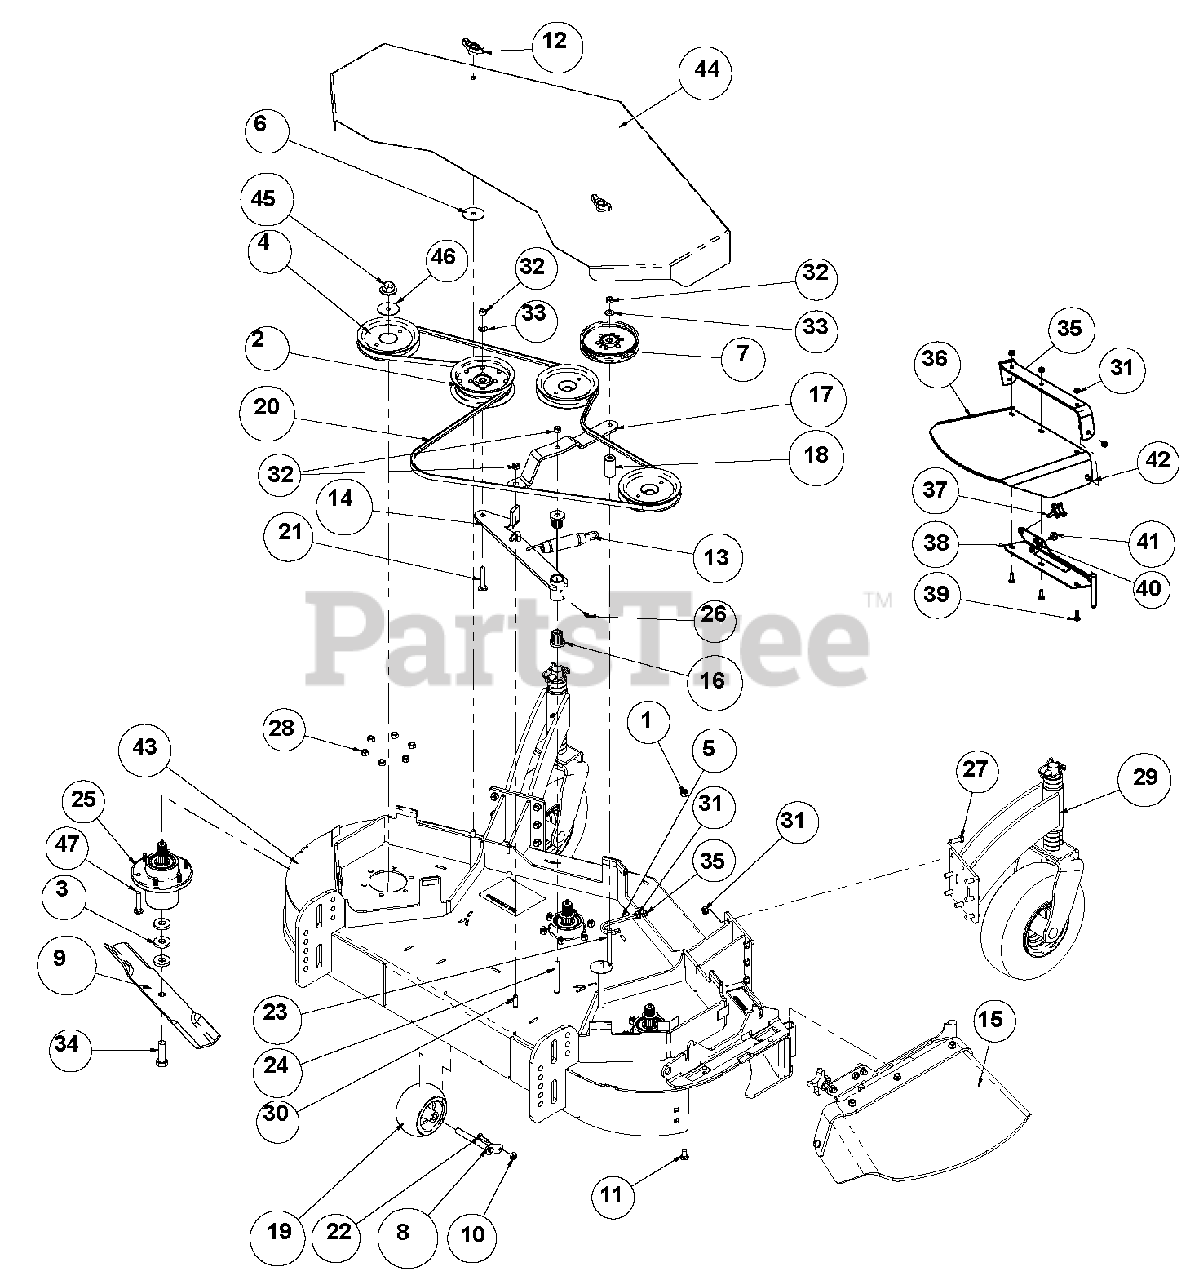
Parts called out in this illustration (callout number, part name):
1	Lochnut, .38-16 Nyloc
2	Pulley, Flat 5.0 x .38 W/Bearing
3	Washer, Blade
4	Pulley, Spline Spindle LSE
5	J-Bolt, 3/8-16 x 4.00 Y
6	Washer, .402 x 2.00 x .055 Fend Y
7	Pulley, FLAT 5.00 x .375 W/Bearing
8	Pivot, Retainer Weld
9	Blade, 18"
10	Nut-1/4" Flange Prevailing Tor
11	Bolt, .38-16 x .750 CRG 5
12	Knob, Locking
13	Spring, Tension
14	Arm, Idler
15	Assembly, Discharge Shield
16	Bearing, FLG M10 x M25 x M27 Fluted
17	Strap, Idler Pulley
19	Wheel, Gage
20	BELT, HB 109.3 EL AMD
21	Bolt, 3/8-16 x 2.25 CRG 5 Y
22	Bolt, 1/4-20 x 1.00 SQU SN Y
23	Bolt, 3/8 x 4 Short Neck Round Head
24	Bolt, 3/8-16 x 3.50 CRG 5 Y
25	Assembly, Spindle Housing
26	Fitting, 1/4-28 Straight Grease Zerk
27	Bolt, 3/8-16 x 1.00 Hex 5 Y
28	Nut, 3/8-16 STD Hex GR5 Y
29	Assembly, Wheel & Strut (see page 26 for parts)
30	Bolt, 3/8-16 x 1.25 CRG 5 Y
31	Locknut, 3/8-16 Whiz Y
32	Locknut, 3/8-16 Crown Y
33	Washer, .406 x .813 x x .065 Flat Y
34	Bolt, Hex .62-11 x 2.00 Grade 8
35	Strap, Rubber Discharge
36	Shield, Rubber Discharge
37	Knob, 3/8 x 1.25-4 Prong
38	Weldment, Discharge
39	Bolt, Round Head Square Neck .38-16 x 1.25 Grade 5
40	Locknut, 5/16-18 Whiz
41	Bumper, Rubber
42	Bolt, Round Head Square Neck .38-16 x 1.00 Grade 5
43	Weldment, 52 Gravely Deck w/Decals
44	Weldment, 52 Gravely Deck Shield w/Decal
45	Locknut, 3/4-16 Crown
46	Washer, .75 x 1.312 x .120
47	Bolt, .38-16 x 1.25 Round Head Square Neck
